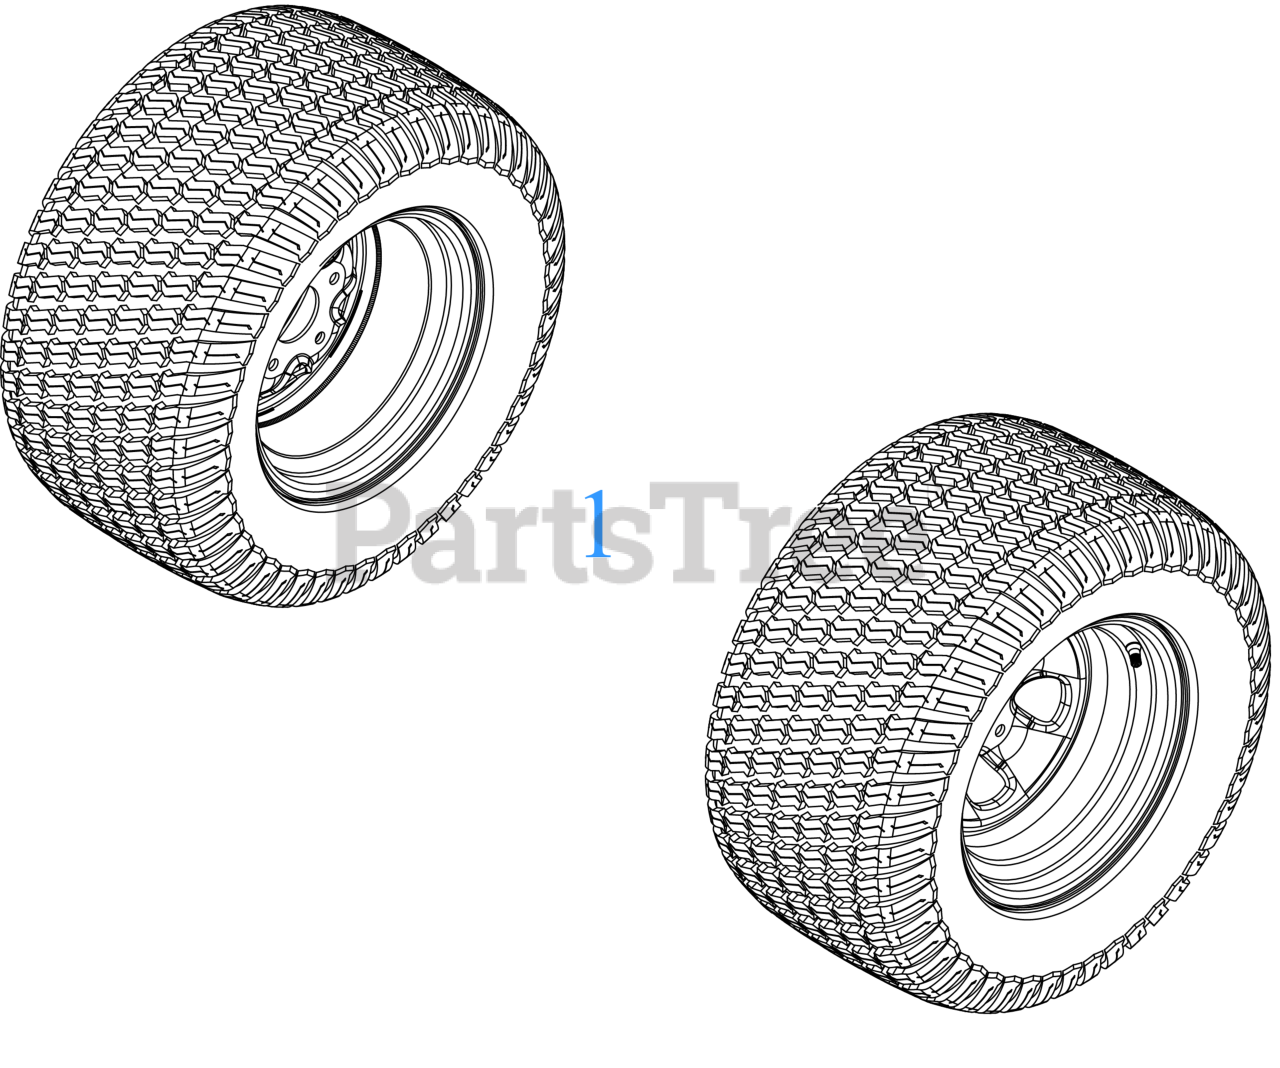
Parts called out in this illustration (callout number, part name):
1	WHEEL ASSEMBLY (23x12-12) (TURFMASTR)
1	RIM ASSEMBLY (12x9)
1	TIRE (23x12-12) (4PLY) (TURFMASTR)
1	TUBELESS AIR VALVE
